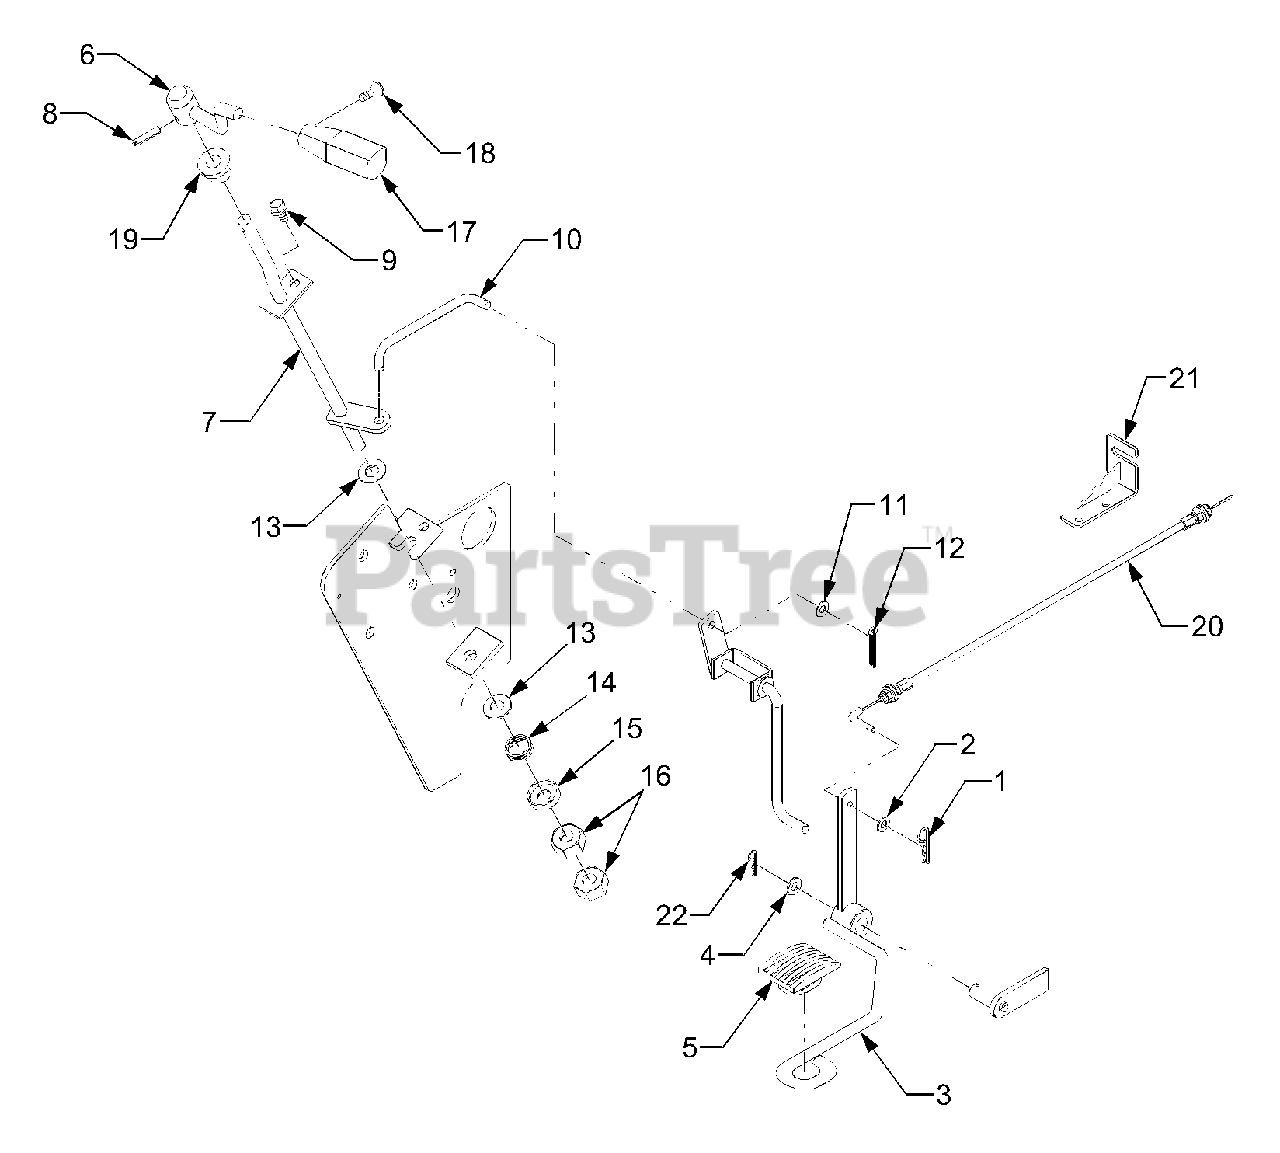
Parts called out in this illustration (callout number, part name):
2	Washer, Plain
4	Washer, Plain
5	Rubber, Accel Pedal
6	Lever 1, Hand Accel
7	Lever 2, Hand Accel
10	Rod, Connector
11	Washer, Plain
13	Washer, Plain
17	Grip (Hand Accel)
20	Cable, Accelerator
